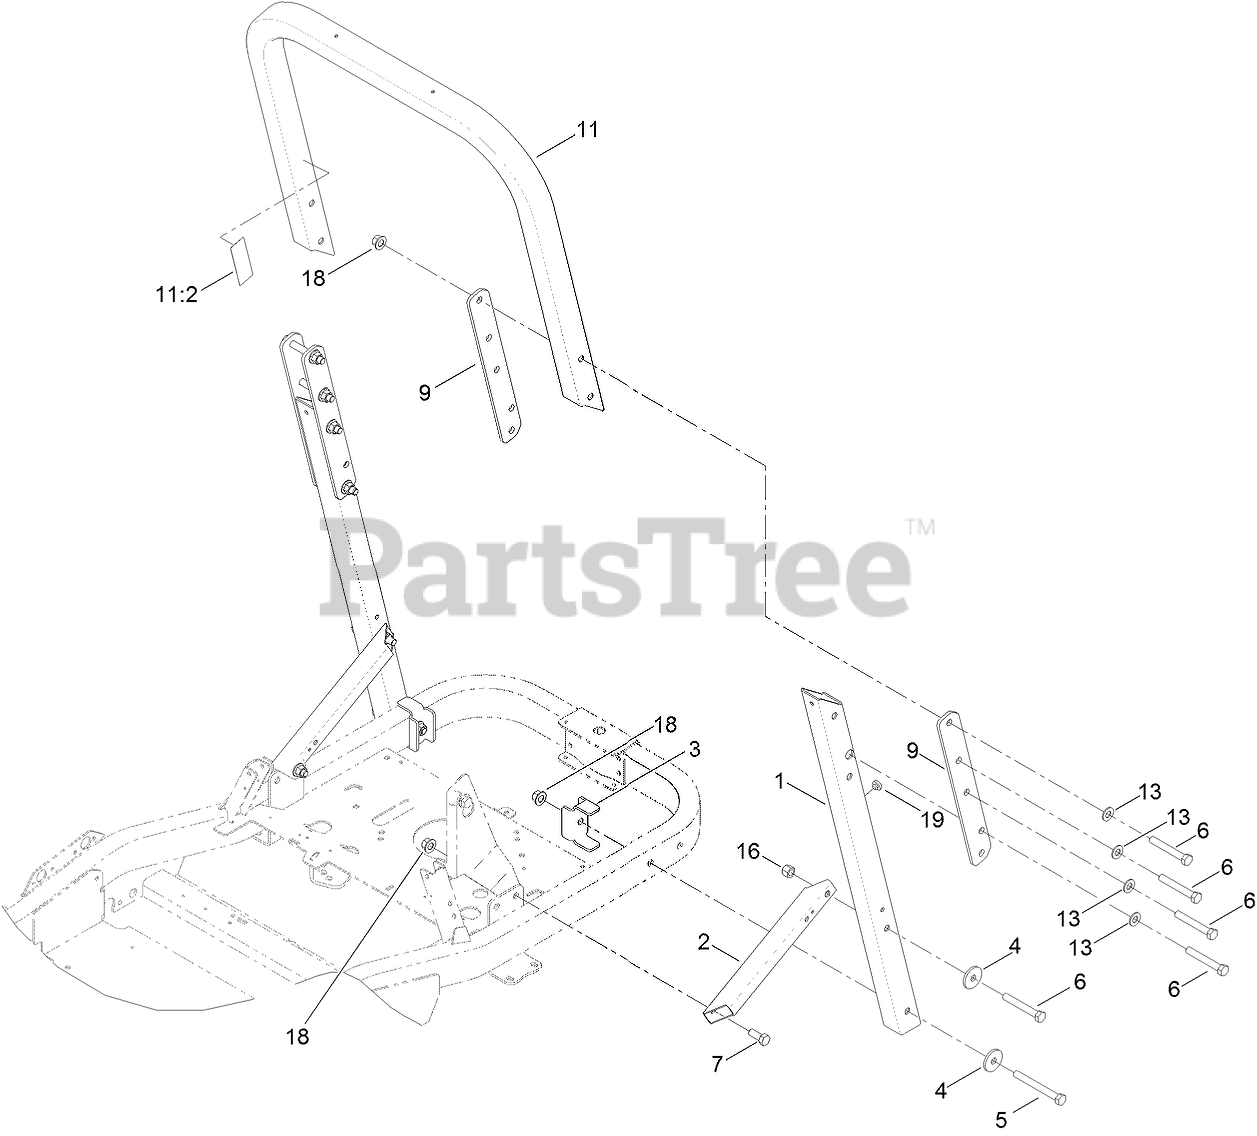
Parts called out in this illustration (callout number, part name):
1	TUBE-ROPS, LOWER
2	TUBE-SUPPORT, ROPS
3	BRACKET-REINFORCING
4	WASHER-THRUST
5	SCREW-HH
6	SCREW-HH
7	SCREW-HH
9	PLATE-ROPS
11	UPPER ROPS ASM
11:2	DECAL-ROPS, WARNING
13	WASHER-FLAT
16	NUT-HEX
18	NUT-LOCK
19	BUMPER
